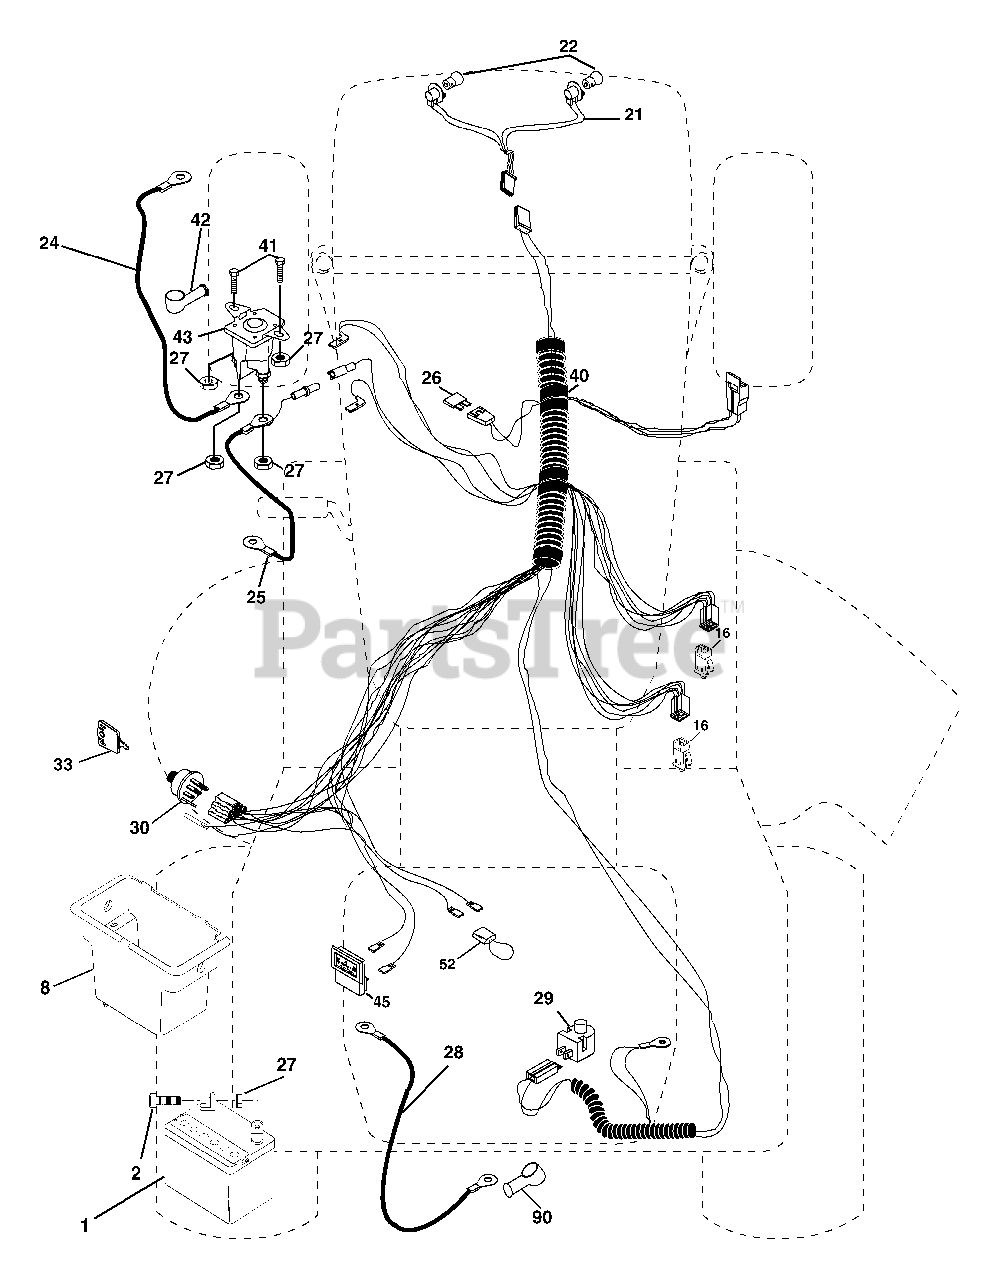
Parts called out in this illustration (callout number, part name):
1	Battery 12 Volt 25 Amp
2	Bolt Hex Hd 1/4-20 unc x 3/4
8	Box Battery
16	Switch Interlock Push -In
21	Harness Asm Light W/4152J
22	Bulb Light #1156
24	Cable Battery 6 Ga. 11"red
25	Cable Battery 6 Ga. w/16 wire,red
26	Fuse 20 AMP
27	Nut Keps Hex 1/4-20 unc
28	Cable Ground 6 Ga. 12" black
29	Switch Plunger Nc Gray
30	Switch Ign
33	Key Ign
40	Harness Ign
41	Bolt Blk Fin Hex 1/4-20 x 1/2
42	Cover Terminal Red
43	Solenoid
45	Ammeter
52	Protection Wire Loop
90	Cover Terminal
